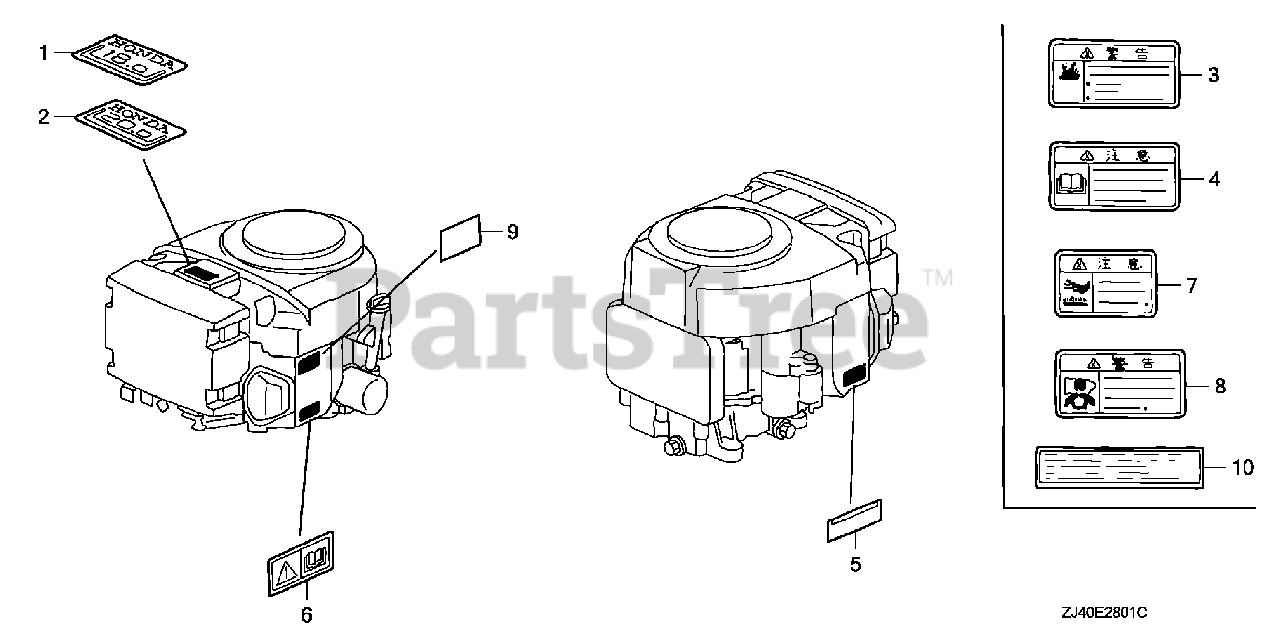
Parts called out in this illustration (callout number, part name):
2	MARK, EMBLEM (GX620)
3	MARK, FUEL WARNING
4	MARK, CAUTION (JAPANESE)
5	LABEL, SPECIFICATION (GXV620)
7	MARK, HEAT CAUTION
8	MARK, EX. GAS WARNING
10	LABEL, CAUTION (ENGLISH, ETC.)
